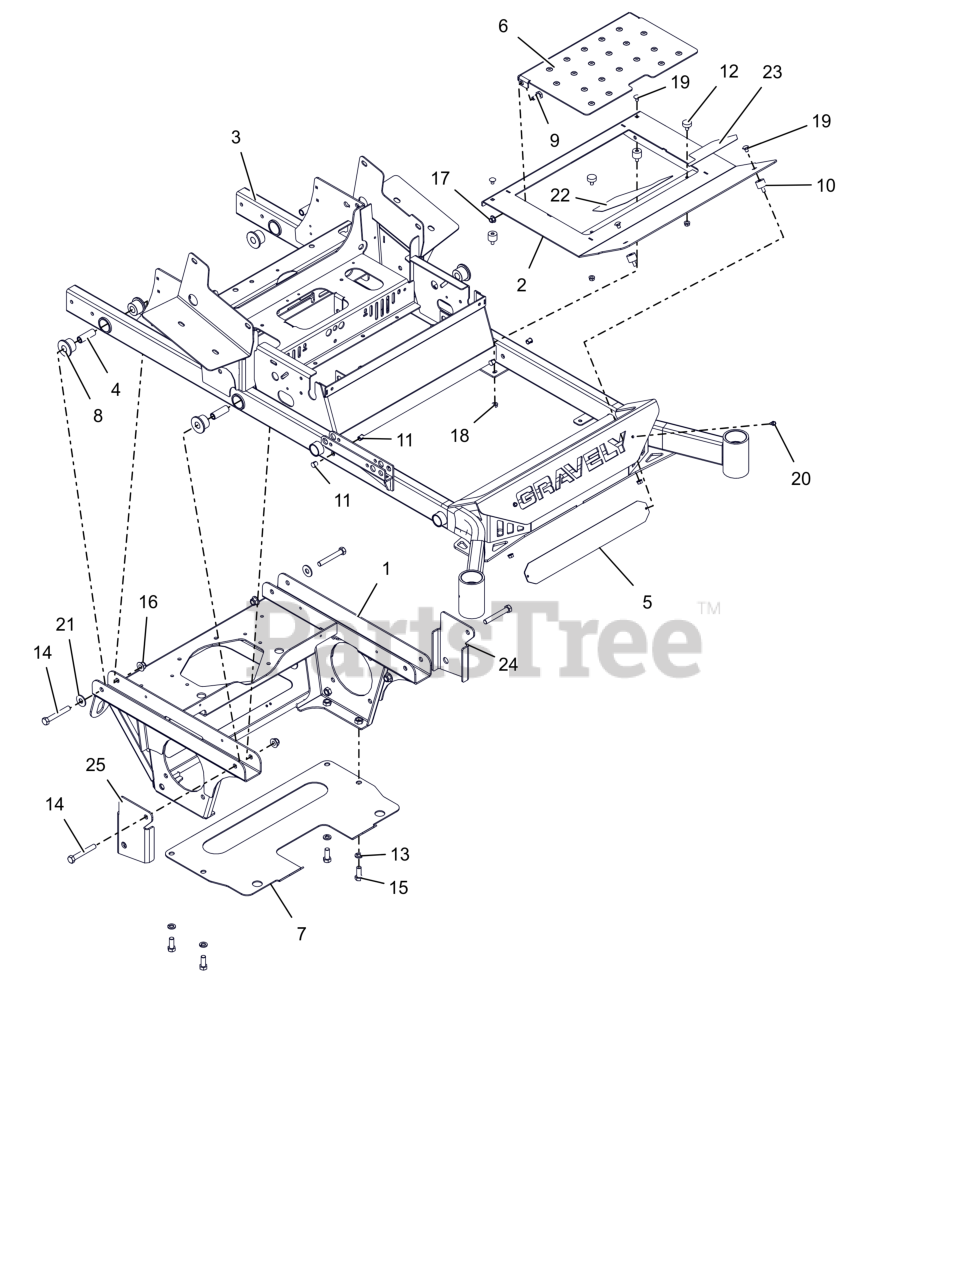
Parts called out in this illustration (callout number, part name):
1	PT200/400 AXLE/ENG FRM WMT-RED
2	FOOTPLATE WLDMT W/SAFETY DECAL
3	52-60"PT200/400 FRAME W/DECALS
4	BSHG-SLV .50X.75X2.23
5	BUMPER LOGO BACKING PLATE -BLK
6	INSPECTION PANEL W/SAFTY DECAL
7	PLATE-TRANSMISSION SKID
8	BSHG-FLG .75X1.51X1.13X2.0 URE
9	BLT,SHLDR EP .38-16X.30 HEX YZ
10	BUMPER,STUD MNTD W/FEMALE INSR
11	PLUG, HOLE .50
12	BUMPER, RUBBER
13	WSHR,LK-REG .500X.125 ZCC
14	BLT, HEX .50-13X3.50 G5 ZCC
15	BLT,HEX .50-13X1.25 G5 ZCC
16	NUT,NYL-FLG .50-13 GF ZCC
17	NUT,NYL-FLG .38-16 GF ZCC
18	NUT,SPNLK-FLG .31-18 G5 ZCC
19	BTL,RHSN .313-18 X 0.5 G5 ZCC
20	SCR-TAP .25-20X.50 HWH ZCC
21	WSHR,FLT .563X1.375X.109 ZCC
22	GRIP, RH FOOT PLATE
23	GRIP, LH FOOT PLATE
